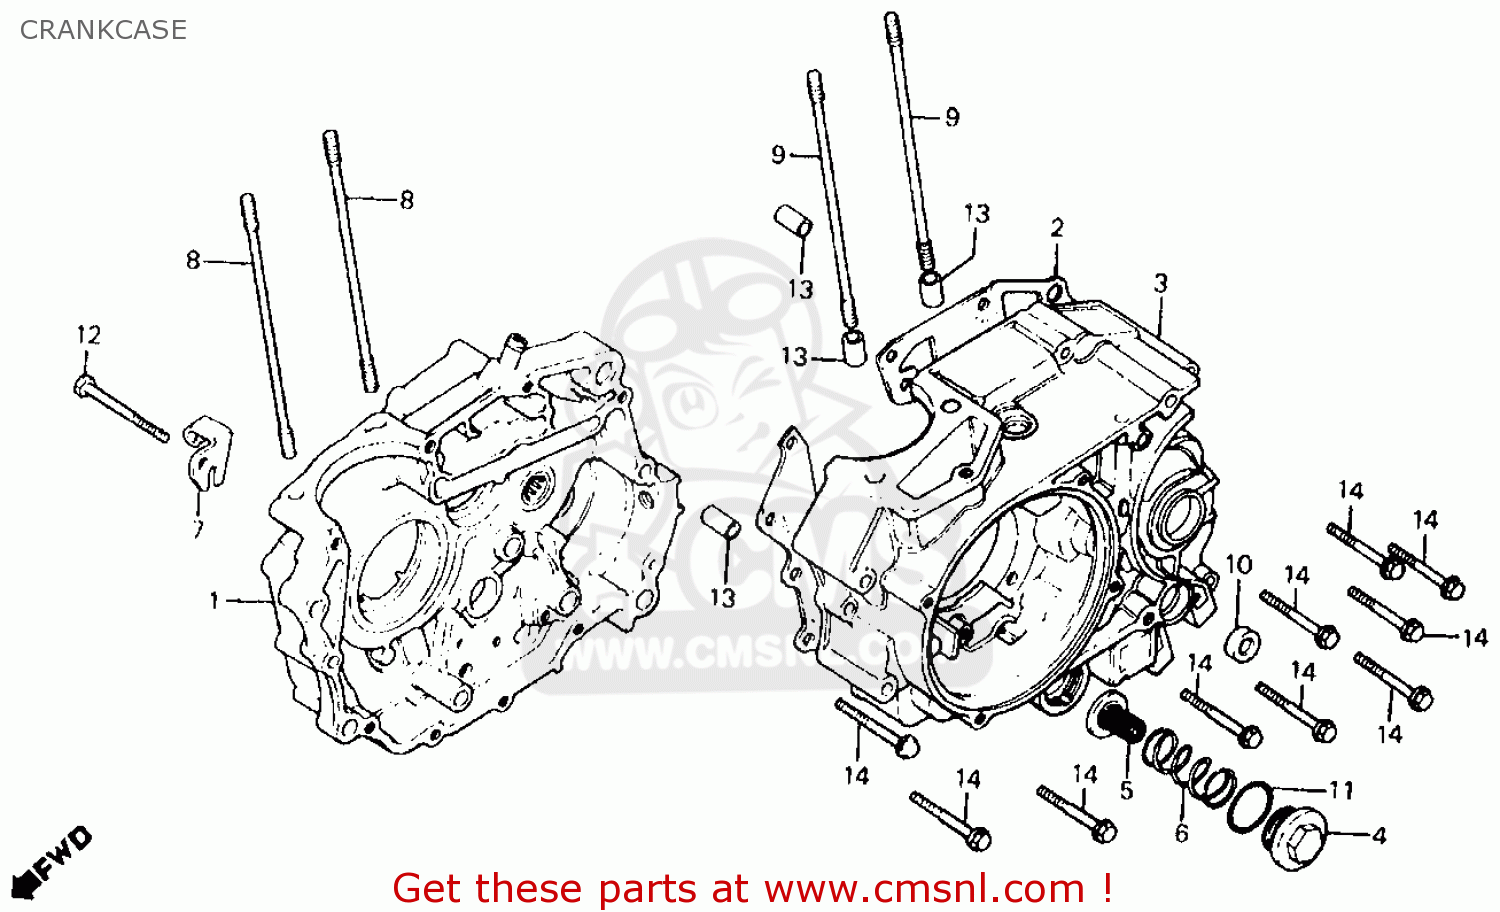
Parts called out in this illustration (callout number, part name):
1	CRANKCASE COMP.,R
2	GASKET,CRANKCASE (MCA)
3	CRANKCASE,COMP.,L
4	CAP,HOLE
5	SCREEN,OIL.FILTER
6	SPRING,SCREEN
7	HOLDER,CLUTCH
8	BOLT A CYLIN,STUD
9	BOLT BCYLIN,STUD
10	OIL SEAL,14X28X7
11	O,RING.3,OX35
12	BOLT,HEX 6X60
13	DOWEL PIN
14	BOLT,FLANGE,6X50
